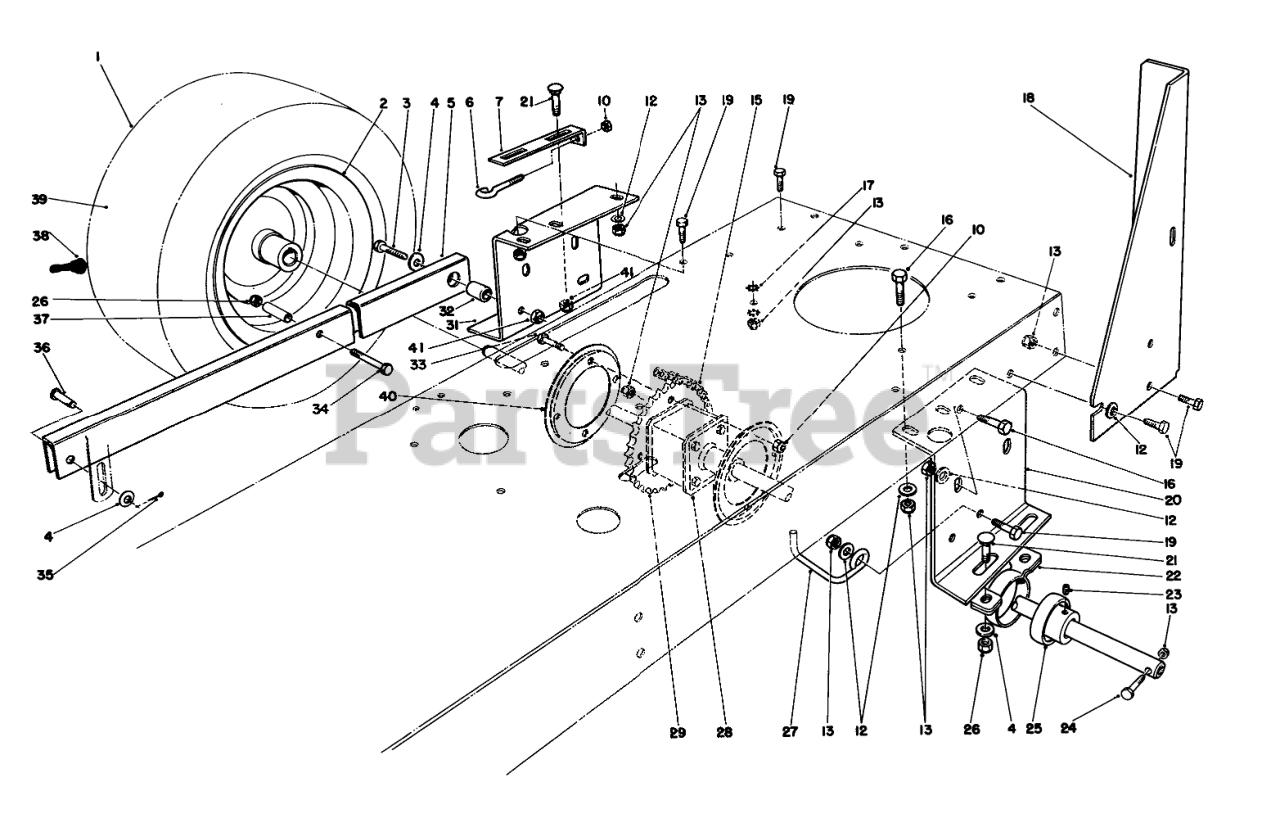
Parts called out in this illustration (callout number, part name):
3	SCREW-HH
4	WASHER-FLAT
5	Arm-Suspension R.H.
6	SCREW-ADJUSTING
7	PLATE-ADJUSTING
10	NUT-HEX
12	WASHER-PLAIN
13	NUT-LOCK, NI
15	ROLLER CHAIN
16	SCREW-HH
17	WASHER-LOCK, INTERNAL
18	LH STANDBAR B
19	SCREW-HH
20	LH REAR AXLE SUPT R
21	BOLT-CARR
22	RTNR-PILLOW BLK
23	SCREW-SET, HSH
24	AXLE MTG BOLT
25	Bearing-Ball (Incl. Ref. #23)
26	NUT-LOCK, NI
27	BELT GUIDE
28	DIFFERENTIAL
29	SPROCKET
31	RH AXLE SUPPORT R
32	PIN-SUPT ARM
33	SCREW-HH
34	SCREW-HH
35	PIN-COTTER
36	PIN-CLEVIS
37	SPACER-SPLIT TUBE
38	STEM-VALVE
39	TUBE-INNER
40	Guide-Chain
41	NUT-LOCK, NI
